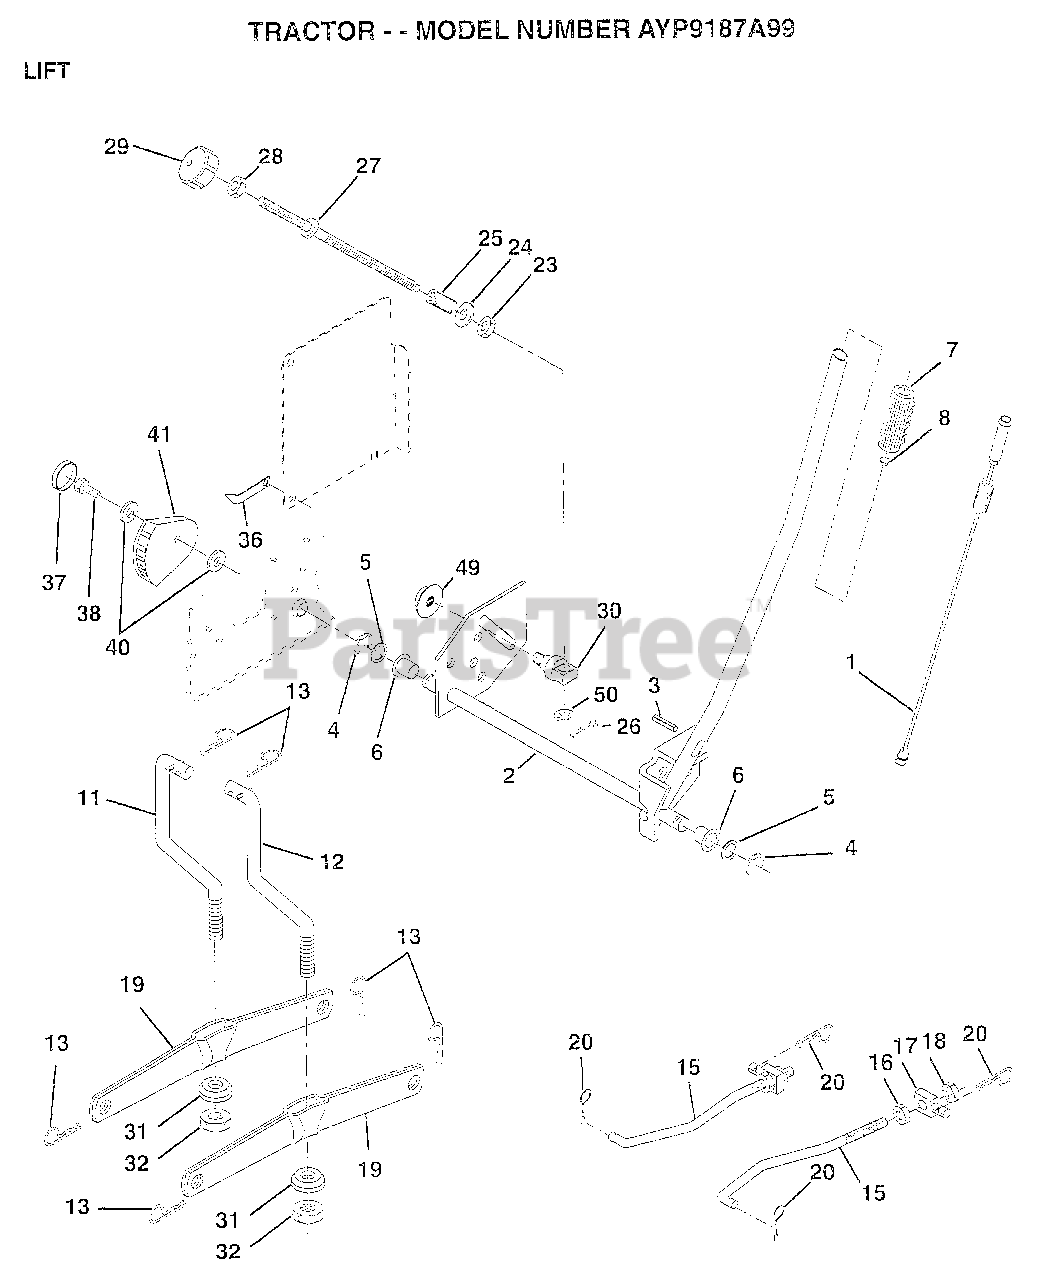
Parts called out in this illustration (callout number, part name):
1	WIRE ASM W.SPRING
2	"SHAFT ASM LIFT,RH"
3	PIN-GROOVE LT
5	WASHER
6	NYLON BEARING
7	GRIP HANDLE
15	LINK.FRONT
16	NUT
17	TRUNION
18	NUT.LK.W/WSH.1/2.
19	ARM SUSP REAR
20	RETAINER SPRING
23	NUT T
24	WASHER
25	SPRING T
28	NUT
29	KNOB INF 3/8-16
30	TRUNNION
31	BEARING PVT LH
32	NUT.CROWNLOCK.3/8
36	POINTER-INDICAT
37	"PLUG,HOLE"
38	SCREW
40	WASHER
41	INDICATOR HEIGHT
49	NUT.HXFLG.LOCK.
50	NUT PUSH M
